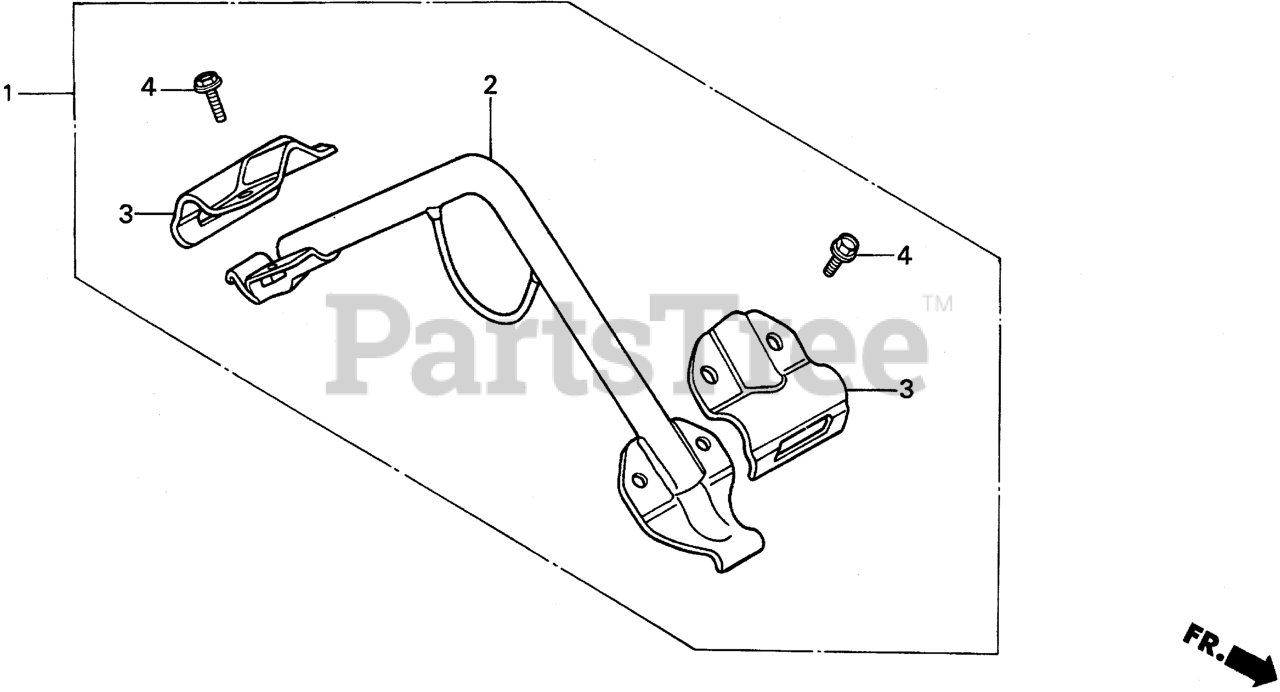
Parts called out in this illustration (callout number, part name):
1	HANGER KIT
2	HANGER
3	BRACKET, HANGER (UPPER)
4	BOLT, FLANGE (8X16) Use from Engine SN 1000016.
